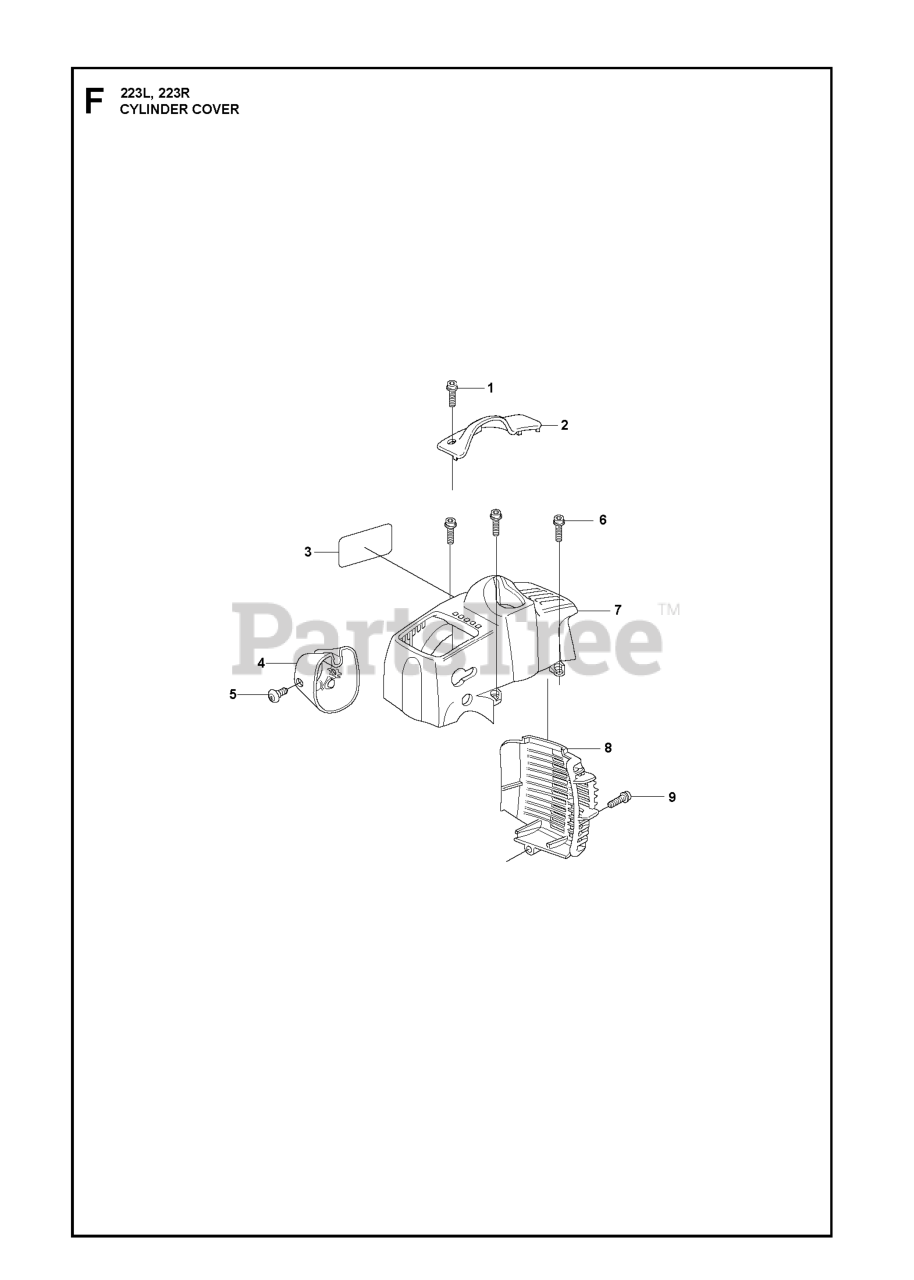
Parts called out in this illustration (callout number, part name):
3	DECAL CYLINDER COVER
3	DECAL, CYLINDER COVER
4	COVER
5	SCREW SPACER
6	SCREW
7	RP CYLINDER COVER
8	MUFFLER COVER
9	SCREW
